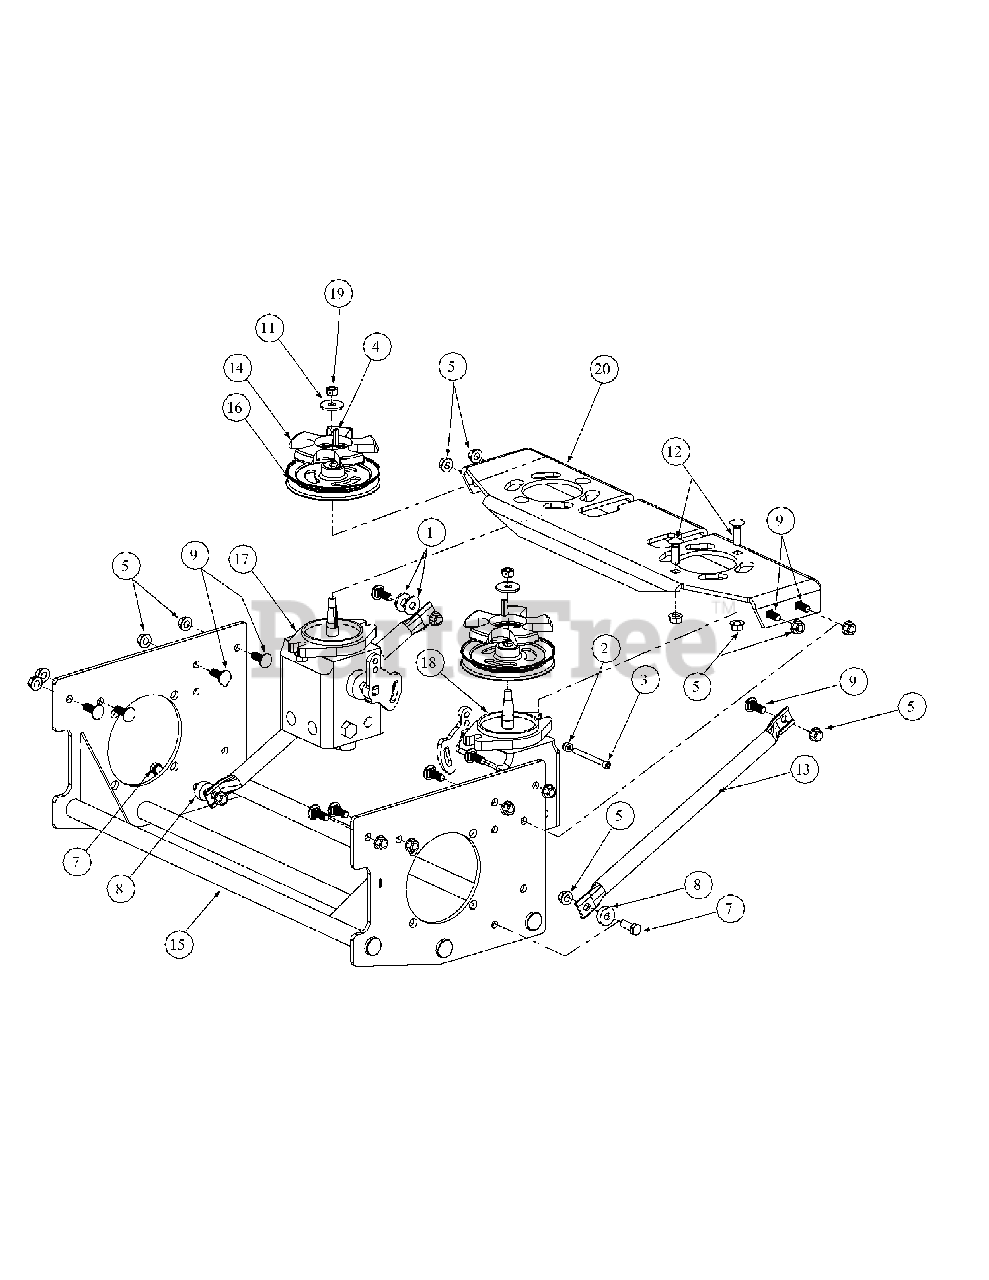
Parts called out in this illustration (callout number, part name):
1	Washer lock 3/8 zinc
2	Lock Nut, Nylon Insert, 1/4-20
3	Socket Head Cap Screw, 1/4-20 x 2-1/2
4	Key, 3/16" x 7/8"
5	Flange Lock Hex Nut, 3/8-16
7	Hex Cap Screw, 2/8 -16 x 1.25
8	Spacer, .406 ID x 1.00 OD x .38
9	Carriage Bolt, 3/8-16 x 1
11	Flat Washer, .411 x 1.25 x .100
12	Carriage Screw, 3/8-16 x 1.25
14	Hydro Pulley Fan
15	Hydro Motor Frame Assembly
16	Hydro Pulley Pump
17	Hydro Pump, LH
18	Hydro Pump, RH
19	Hex Nut, 3/8-24
20	Hydro Pump Mounting Weldment
